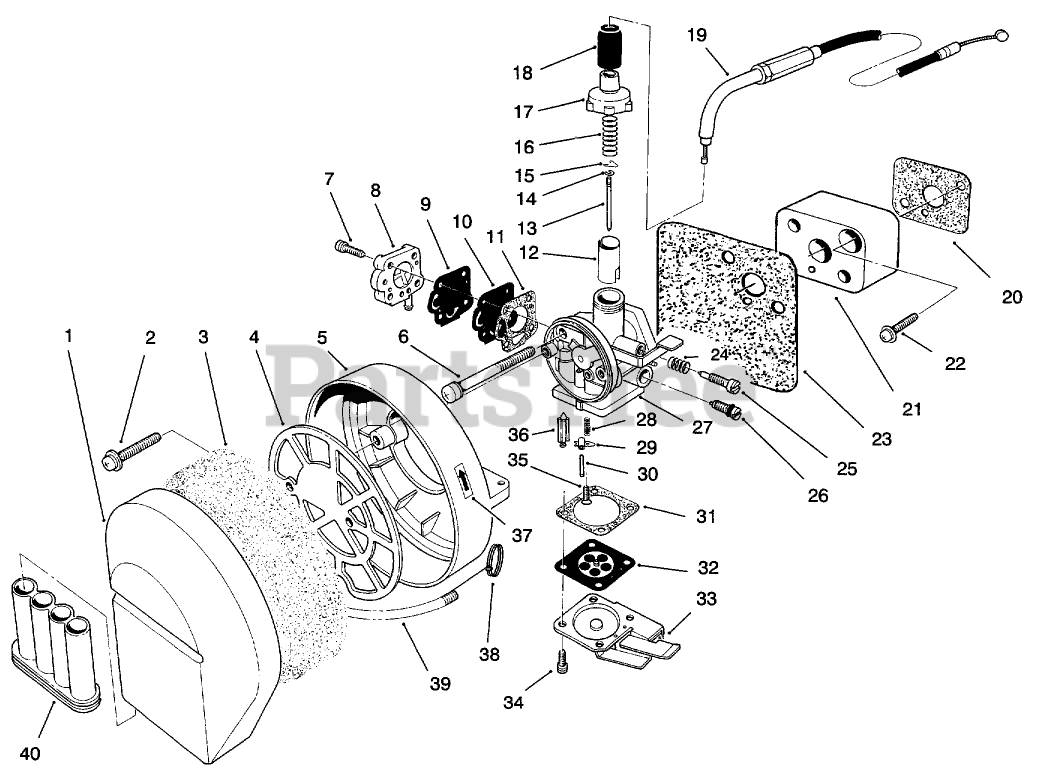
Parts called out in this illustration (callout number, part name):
1	CLEANER COVER
2	SCREW & WASHER
3	CLEANER ELEMENT
5	CLEANER CASE
9	PUMP DIAPHRAGM
10	GASKET-PUMP CHECK VALVE
11	PUMP COVER GASKET
18	AIR SEAL
19	THROTTLE WIRE
20	GASKET
21	INSULATOR
22	SCREW & WASHER
23	CARBURETOR GASKET
24	SPRING
26	MAIN JET NEEDLE ASM
28	SPRING
29	FLOAT ARM
30	FLOAT PIN
31	GASKET
35	FLOAT SCREW
37	CHOKE LABEL
38	SPRING
39	SPRING
